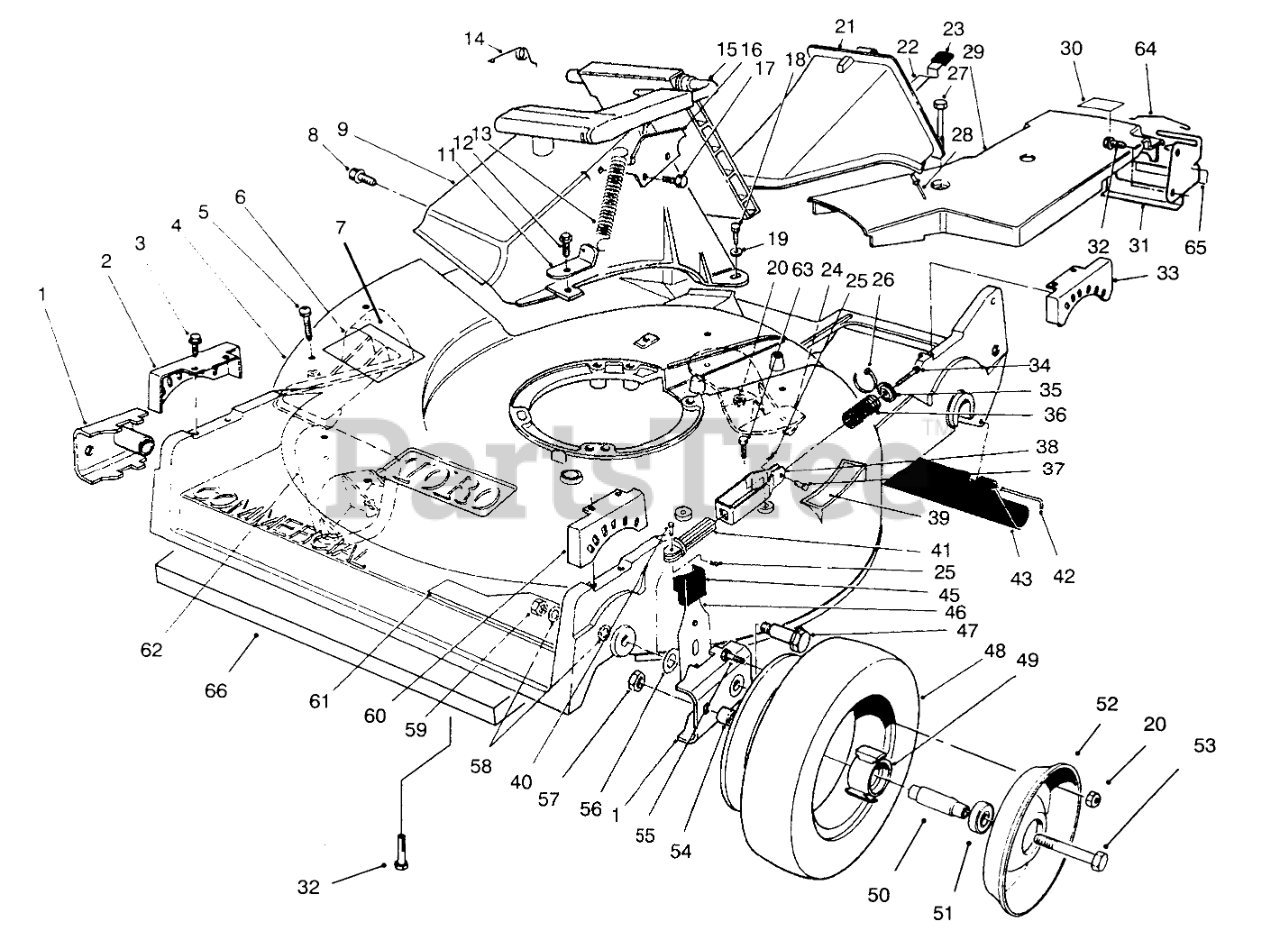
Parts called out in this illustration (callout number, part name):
1	ARM-PIVOT, FRONT
2	QUADRANT-FRONT, RH
3	SCREW-HWHTF
4	Housing-Commercial(Incl. Ref. #5-7,24,62 pg.1-2)(Incl Ref. #28 pg. 4)
5	SCREW-PPH
6	KICKER-RH
7	DECAL-DANGER
8	SCREW AND WASHER ASM
9	TUNNEL-DISCHARGE
11	BRACKET-SPRING
12	SCREW-HWH
13	SPRING-DOOR
14	RETAINER-DOOR
15	DOOR ASSEMBLY
16	DOOR LATCH PLATE
17	SCREW-PLASTITE
18	SCREW-HH
19	WASHER-FLAT
20	NUT-LOCK, NI
21	Plug-Discharge (Incl. Ref. #22, 23, & 28)
22	LATCH-PLUG, DISCHARGE
23	GRIP-LATCH
24	KICKER-REAR
25	PIN-COTTER
26	TIE-CABLE
27	SCREW-HHFTF
28	RIVET-HEAD, FLAT
29	BELT COVER (MACHINED)
30	DECAL-GREASE
31	BRACKET-ADJUSTMENT, TRACTION
32	SCREW-HWHTF
33	QUADRANT-REAR, LH
34	SCREW-HWHTF
35	RETAINER-SPRING
36	SPRING
37	PIN-CABLE
38	Bracket-Spring
39	DECAL - STEP PAD INT'L
40	PIN-SPRING
41	GUIDE-SPRING
42	ROD-SHIELD
43	SHIELD-TRAILING
45	KNOB-ARM
46	FRONT SPRING ARM ASM
47	BOLT-WHEEL
49	HUB-BEARING
50	SPACER-BEARING
51	BEARING-WHEEL
52	Wheel-Half
53	SCREW-HH
54	SPACER-WHEEL
55	SCREW-HH
56	WASHER-THRUST
57	NUT-LOCK, CONE
58	WASHER
59	NUT-LOCK
60	QUADRANT-FRONT, LH
61	DECAL - DECK
62	KICKER-FRONT
63	SCREW-HH
64	RETAINER-CABLE
65	DECAL-POSITION, GEAR
66	Shield-front
